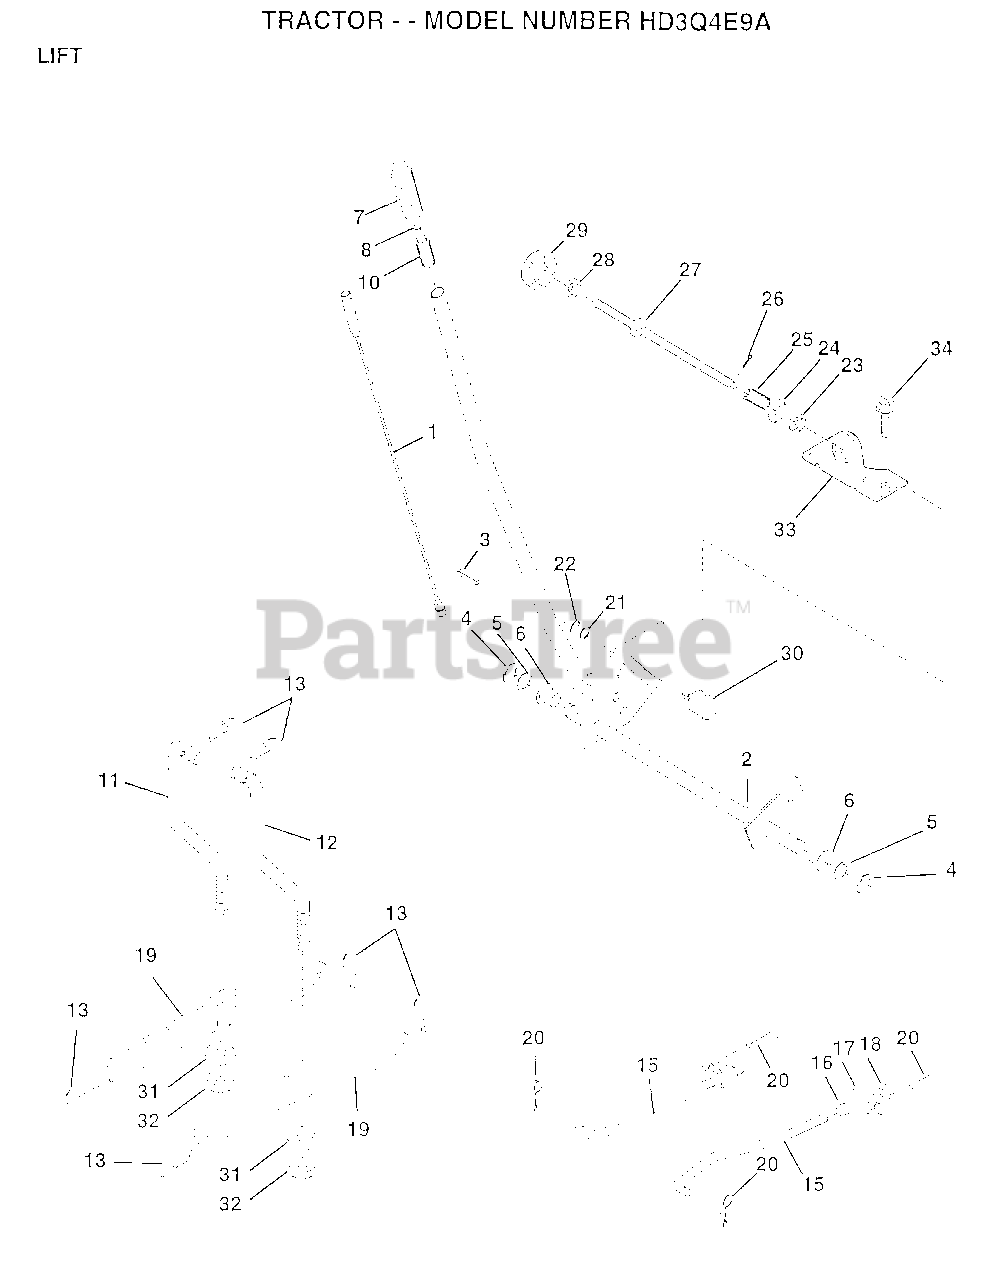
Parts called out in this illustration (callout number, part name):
1	WIRE ASM
2	HANDLE.LIFT.LH.
3	PIN GROOVE
5	WASHER
6	NYLON BEARING
7	GRIP HANDLE
15	LINK.FRONT
16	NUT
17	TRUNION
18	NUT.LK.W/WSH.1/2.
19	ARM SUSP REAR
20	RETAINER.SPRING
21	WASHER
22	KLIP RING
23	NUT T
24	WASHER
25	SPRING T
28	NUT
29	KNOB INF 3/8-16
30	TRUNION LT
31	BEARING PVT LH
32	NUT.CROWNLOCK.3/8
